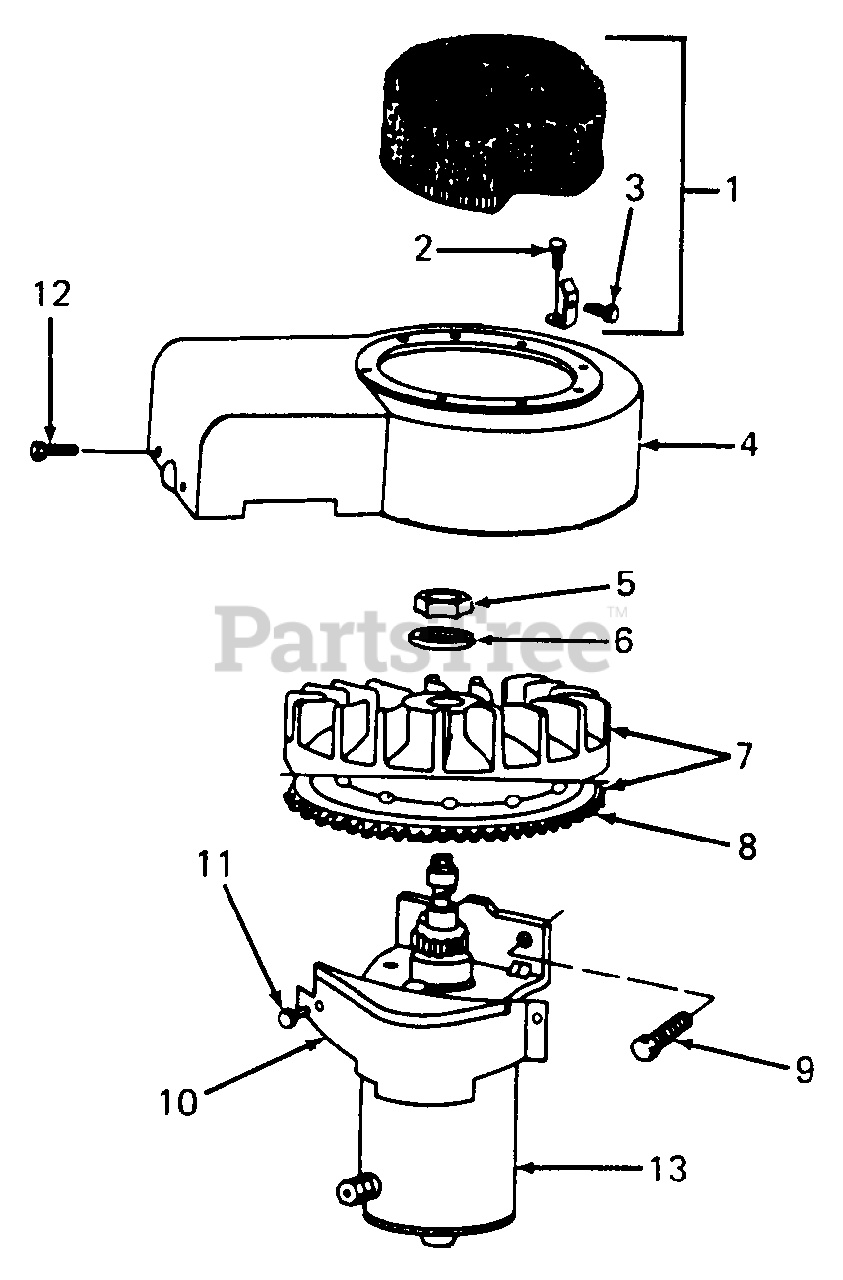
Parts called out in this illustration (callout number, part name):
1	Guard, Debris
2	Screw, Hex Washer Hd
3	Screw, Hex Head Sem
4	Housing, Blower
5	Nut, Hex
6	Washer, Spring
7	Flywheel & Ring Gear Assy, Magneto
8	Gear Ring for Tri-Circuit System
9	Screw Sem
10	Cover, Starter
11	Screw Sem
12	Screw, Blower Housing Mounting Sem
13	Starter Motor
